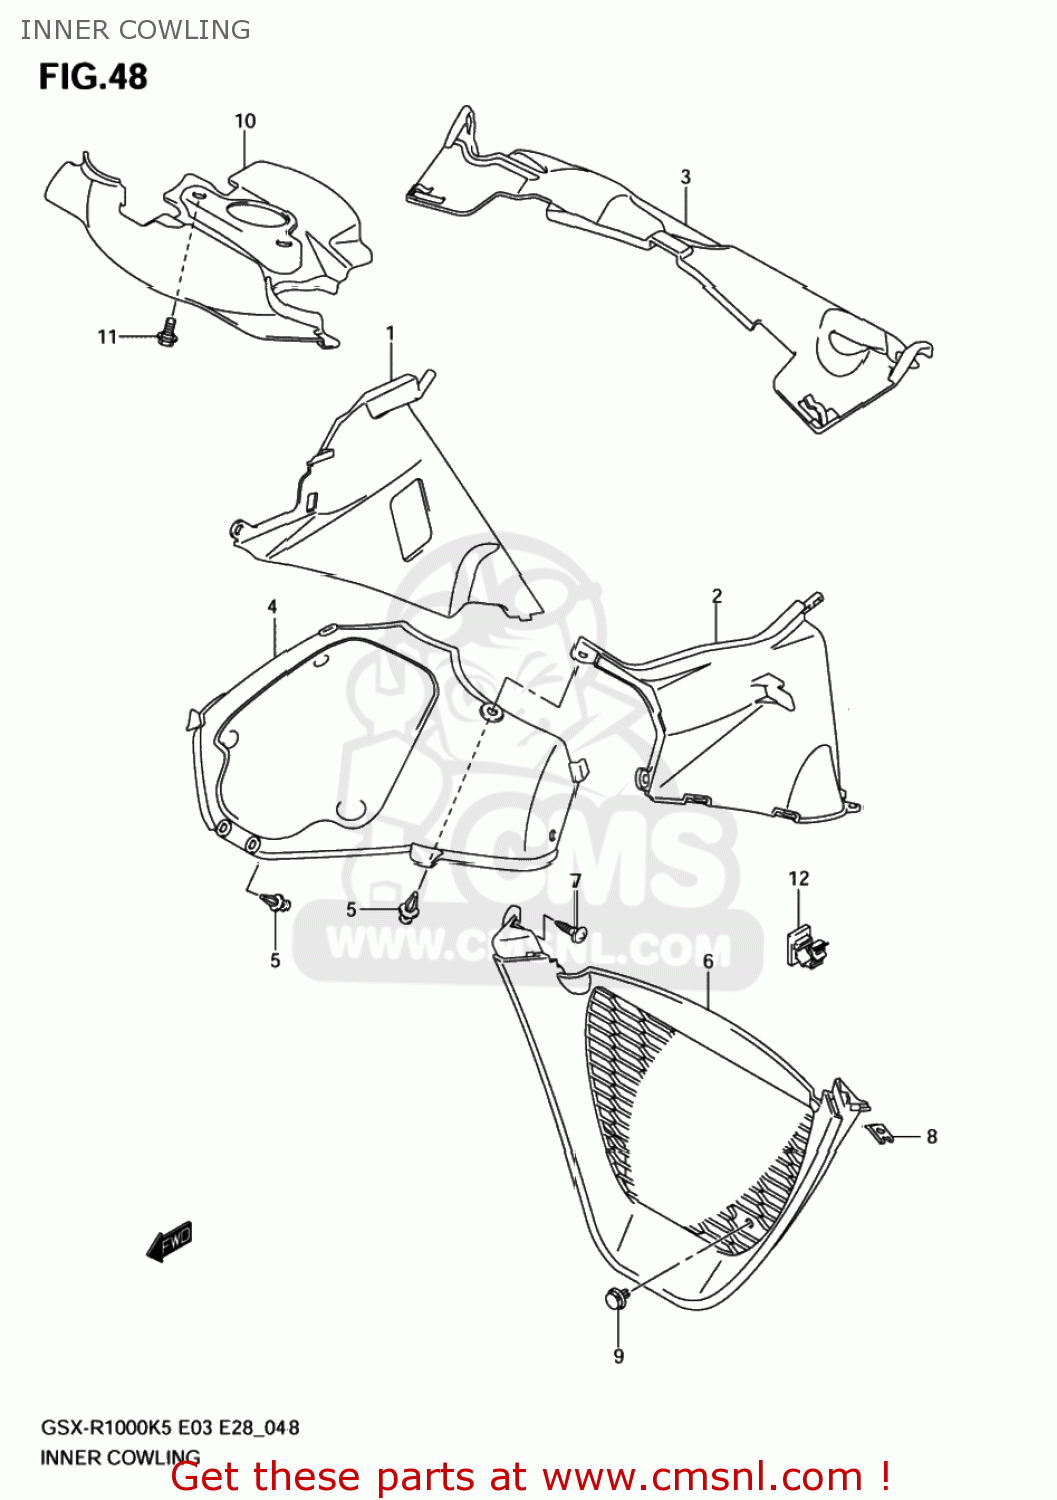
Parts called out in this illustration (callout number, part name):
1	COWLING,UNDER INNER,R
2	COWLING,UNDER INNER,L
3	COVER,COWLING FR LWR
4	COVER,BODY COWLING
5	CLIP(BLACK)
6	COWLING,UNDER CTR
7	SCREW
8	NUT
9	CLIP
10	COVER,LWR BRACKET
11	BOLT
12	CLAMP
